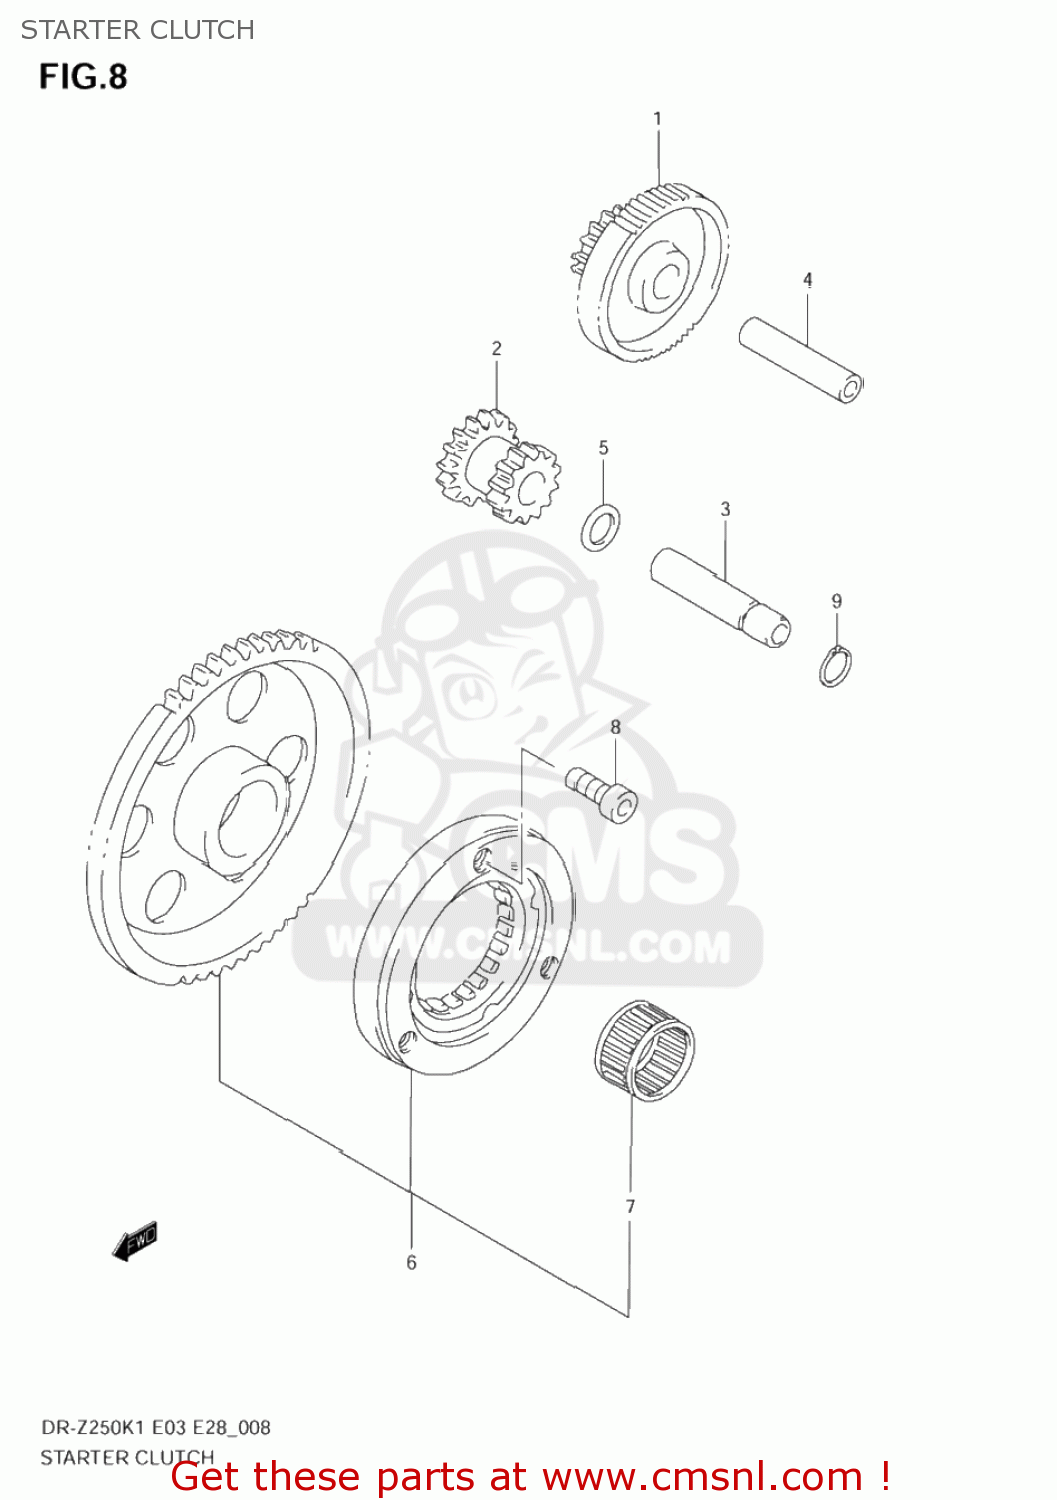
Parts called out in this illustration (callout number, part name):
1	GEAR,STARTER IDLE NO.1
2	GEAR,STRTR IDLE NO.2(NT:12/16)
3	SHAFT, STARTER IDLE GEAR NO.2
4	PIN(7X12X50.5)
5	SHIM(12X18X0.5)
6	CLUTCH SET,STARTER
7	BEARING(25X31X19)
8	BOLT
9	CIRCLIP,12 MM
